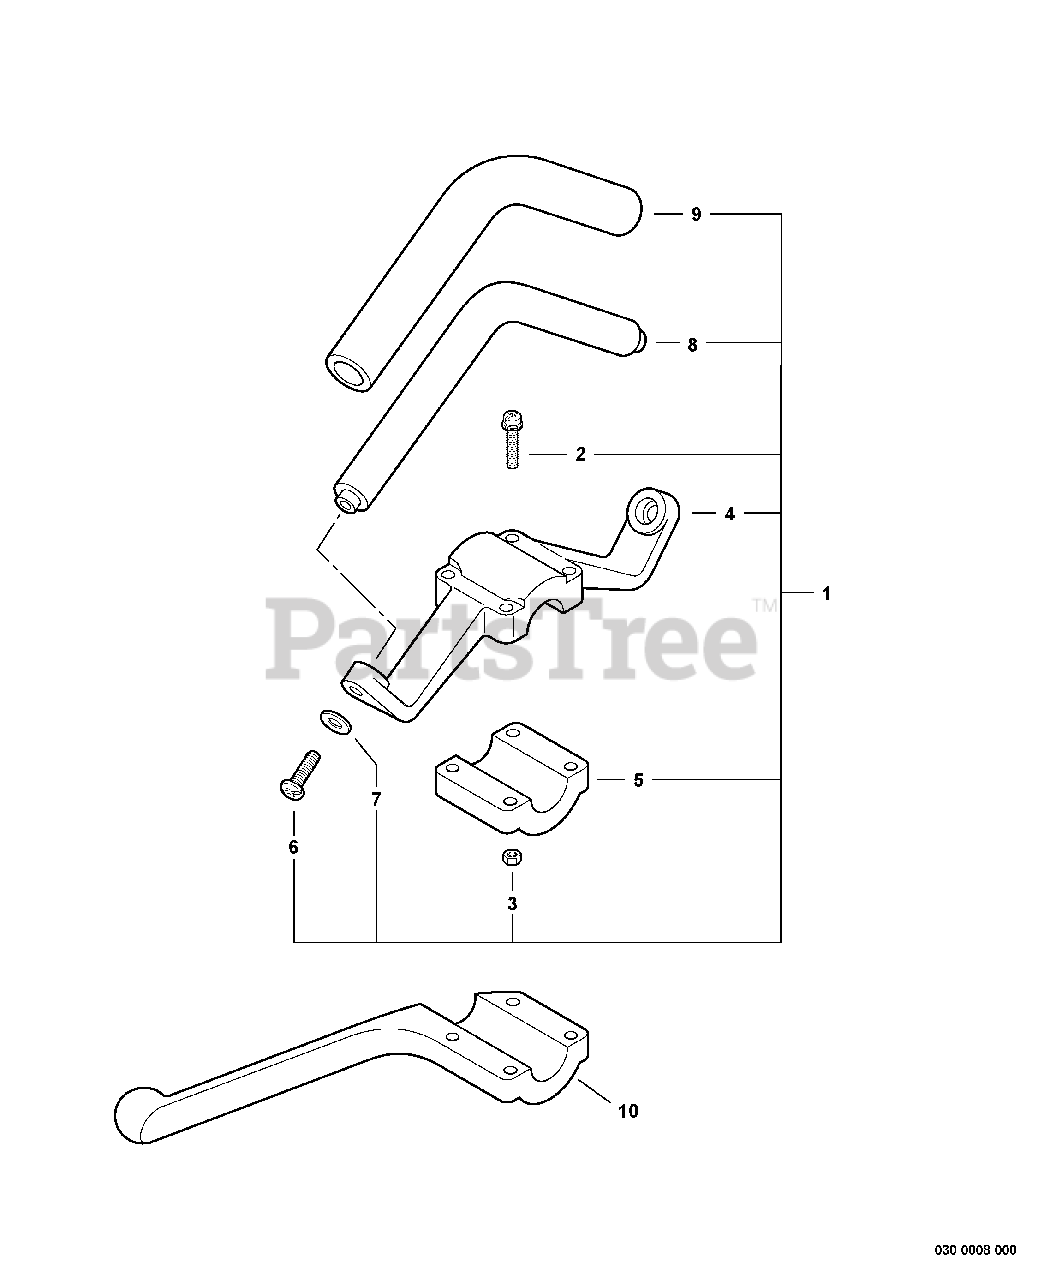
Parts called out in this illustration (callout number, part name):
1	HANDLE ASSY - FRONT
2	SCREW - 5X35
4	BRACKET, HANDLE - UPPER
5	BRACKET, HANDLE - LOWER
6	SCREW - 5X20 -- TAPPING
7	WASHER - 5
8	HANDLE - FRONT
9	GRIP, HANDLE
10	BAR, BARRIER
